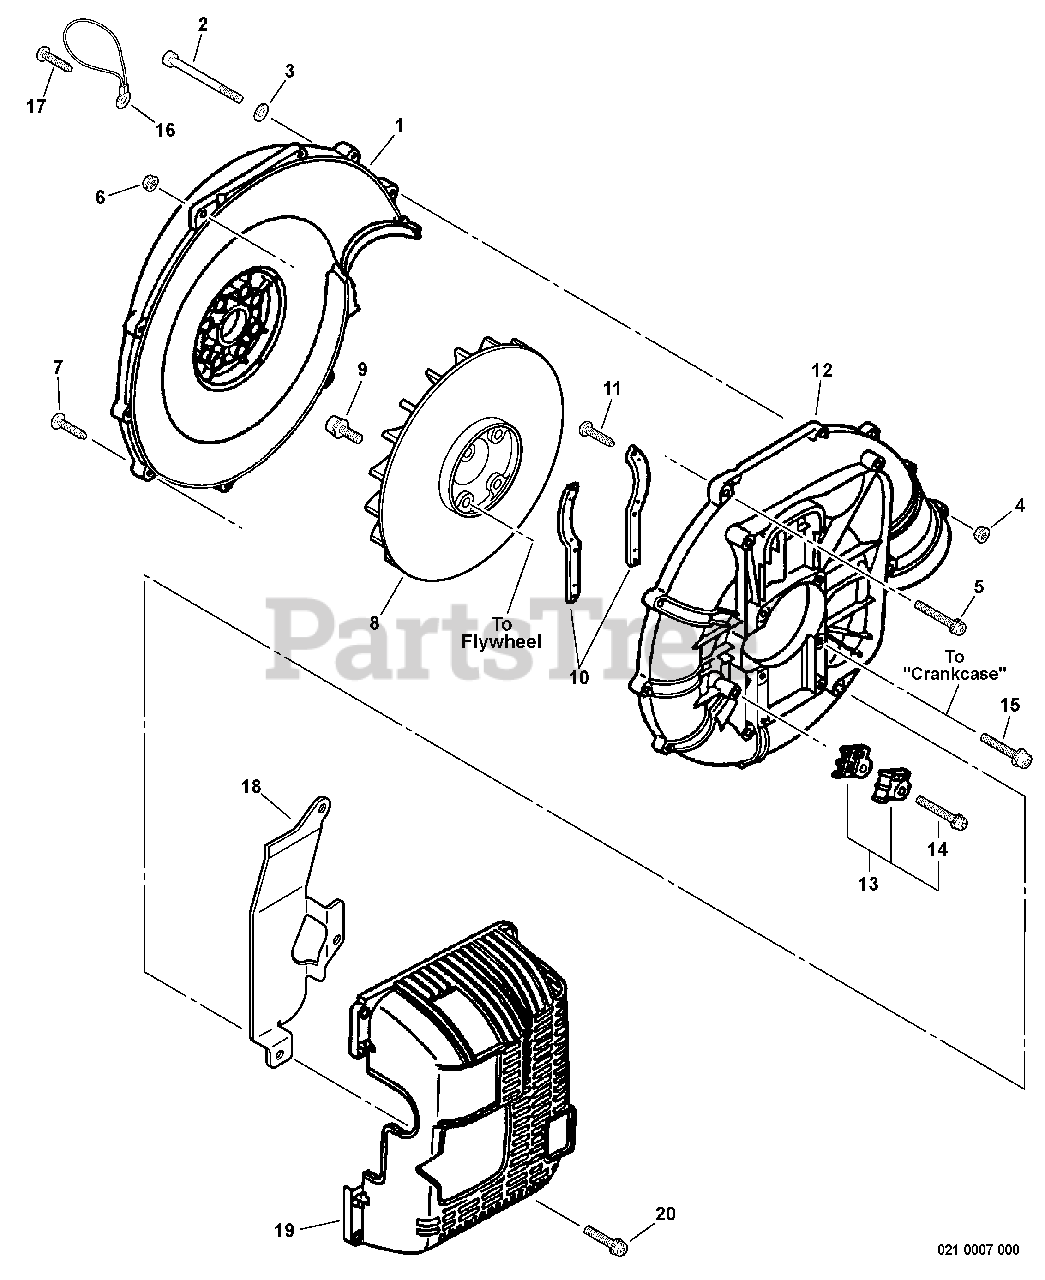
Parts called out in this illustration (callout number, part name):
1	COVER, FAN - INNER -- GRAY
2	SCREW - 5X60
3	WASHER - 5
4	NUT - 5 -- FLANGE
5	SCREW - 5X40
6	NUT - 5 -- FLANGE
7	SCREW - 5X30
8	FAN
9	SCREW - 5X20
10	BRACKET, ENGINE
11	SCREW - 3X12 -- TAPPING
12	COVER, FAN - OUTER -- GRAY
13	CABLE HOLDER KIT
14	SCREW - 5X25
15	SCREW - 5X32
16	STRAP, SAFETY
17	SCREW - 5X16 -- TAPPING
18	INSULATOR
19	COVER, ENGINE
20	SCREW - 5X18
